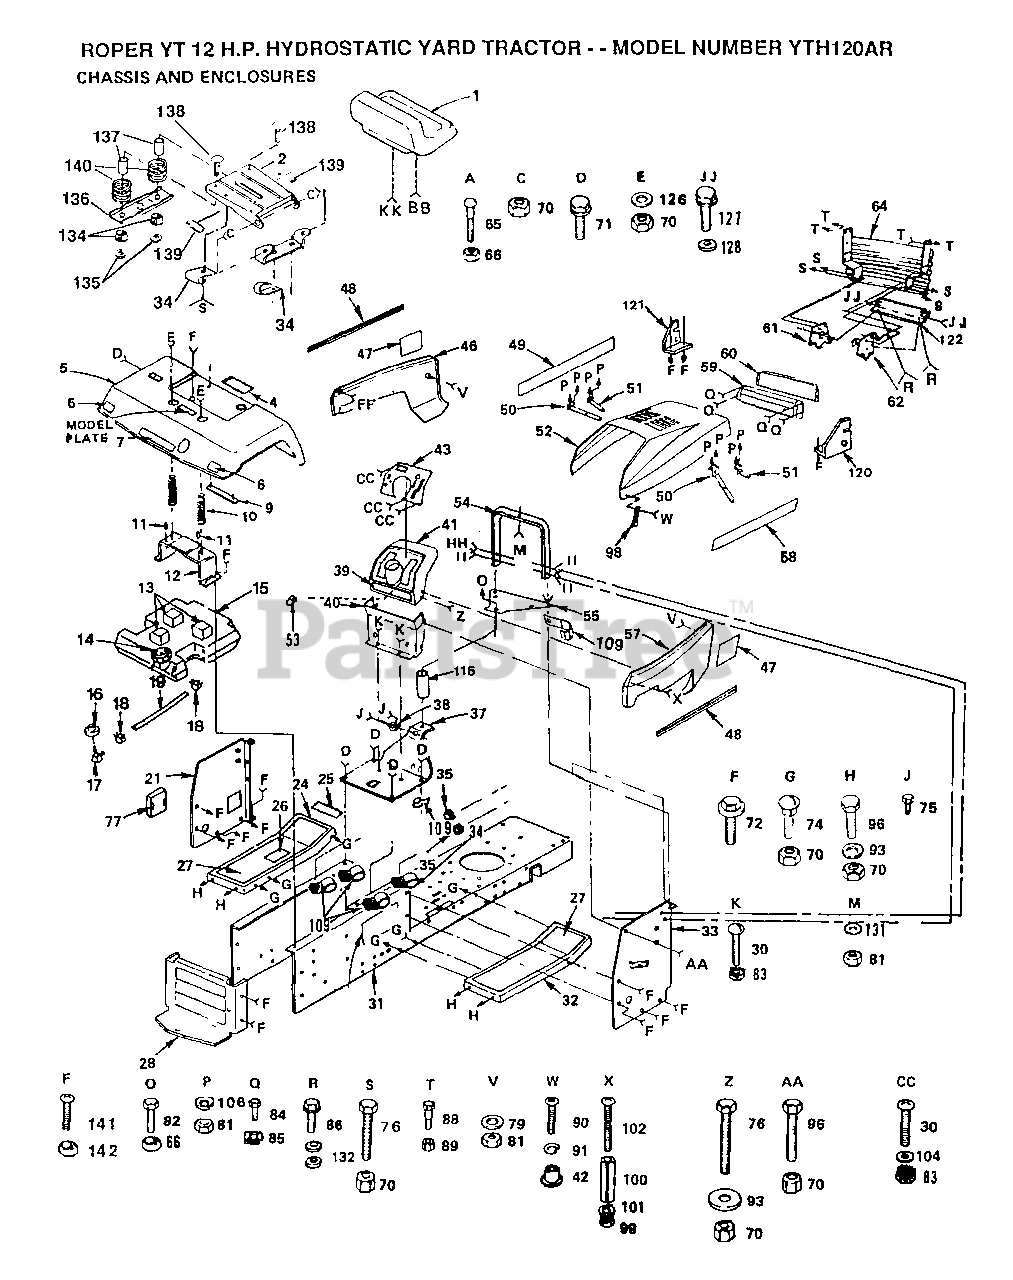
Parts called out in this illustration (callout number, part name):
4	DECAL
6	REFLECTOR-TAIL YT
11	NUT-PUSH YT
12	BRKT FENDER T
13	PAD-SPACER T
16	BUSHING OUTLET T
17	FUEL TANK STEM GT
21	DASH PANEL T
25	DECAL T
30	SCREW
37	SADDLE
39	DECAL YT
40	LOWER DASH
42	WELDNUT
53	PLUG BUTTON T
60	LENS LT
61	SUPPORT LH YTH
62	SUPPORT RH YTH
71	SCREW LT
72	SCREW
74	BOLT
76	BOLT
77	COVER ACCESS
79	WASHER PM
82	BOLT
85	"""J"" FASTENER LT"
86	SCREW
88	BOLT T
90	SCREW
91	LOCKWASHER
93	WASHER
98	HOOD LATCH T
100	SPACER LT
101	WASHER
102	SCREW
104	WASHER
109	CLIP T
116	SPACER
120	SUPPORT RH YTH
121	SUPPORT LH YTH
122	STRAP GRILL
126	WASHER
127	SCREW
128	WASHER PM
132	WASHER
134	BUSHING
135	NUT T
136	BRKT SWITCH
137	SPACER SPLIT
138	BOLT
142	"NUT,KEPS"
